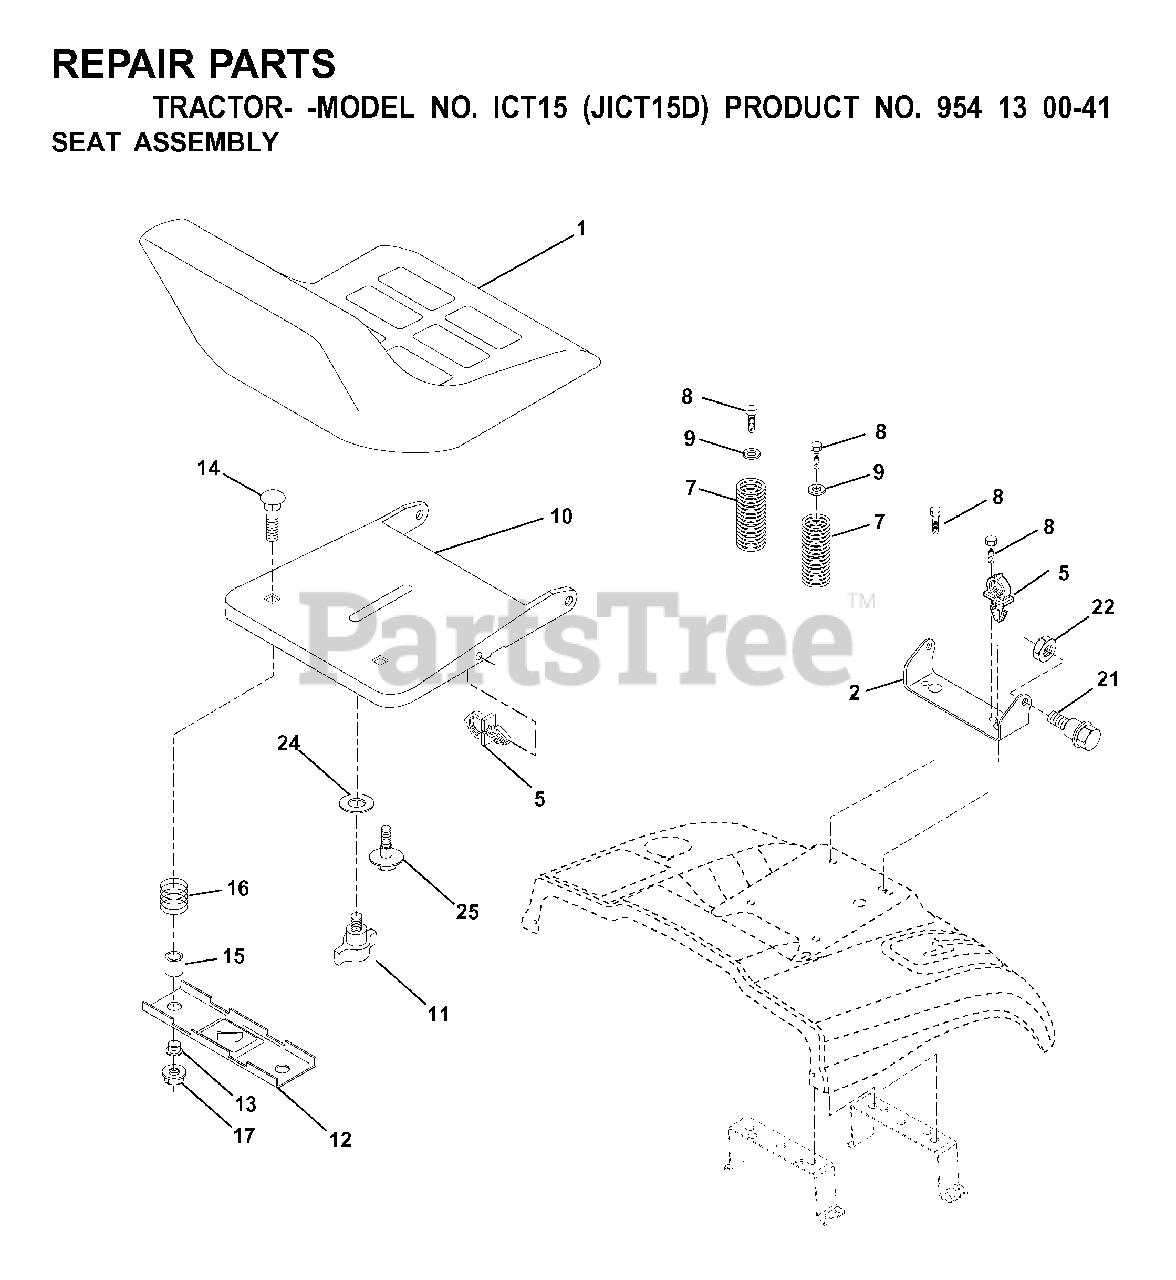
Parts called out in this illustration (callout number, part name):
2	SEAT PIVOT BRKT
5	PUSH CLIP
7	SPRING COMPRESSION
8	SCREW 3/8-16X1
9	WASHER
10	PAN, SEAT
11	KNOB.SEAT.ADJ.WINGNUT
12	BRKT SWITCH
14	BOLT.ROUND.HEAD.SQUARE.NECK
15	SPACER SPLIT
16	SPRING COMPRESSED
17	NUT T
21	BOLT.SHOULDER.5/16-18
22	NUT.71038.31-18.HEX.NYLOCK
25	BOLT,SHOULD
